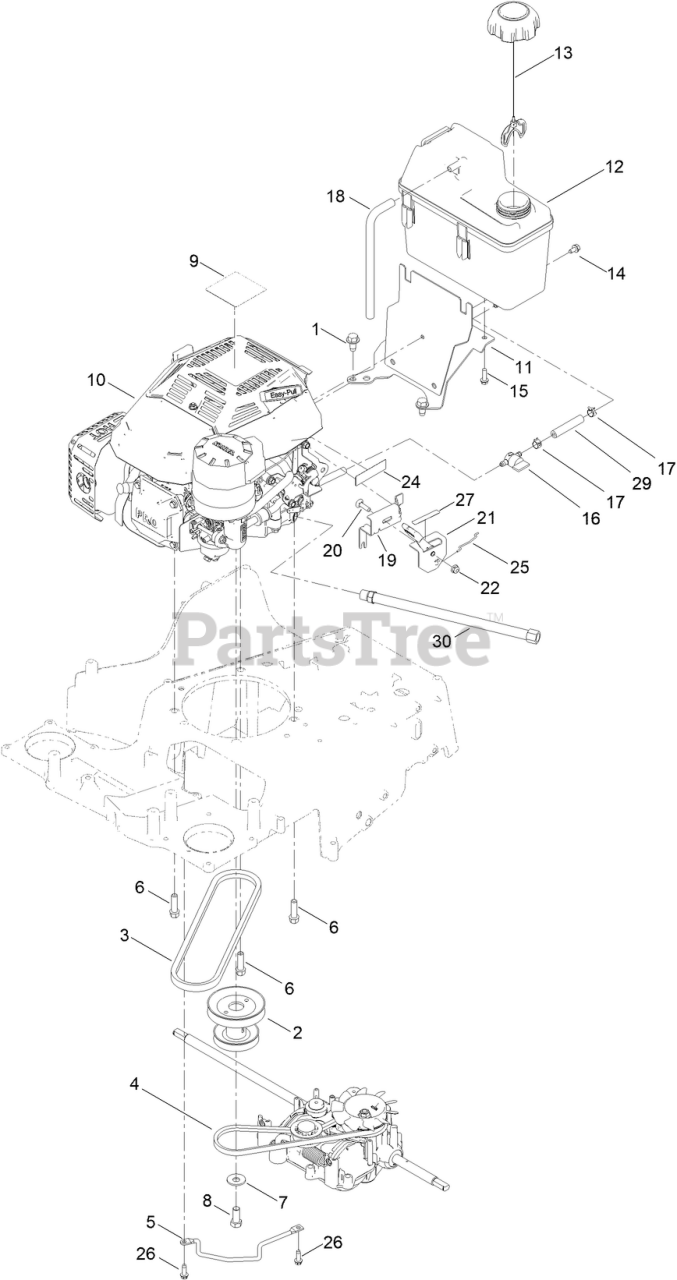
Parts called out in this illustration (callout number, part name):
1	SCREW-HWH
2	PULLEY-ENGINE
3	V-BELT
4	BELT-V
5	ROD-GUIDE, BELT
6	SCREW-TAPTITE
7	WASHER-BELLEVILLE
8	SCREW-HH
9	DECAL-TORO
11	TANK MOUNT ASM
12	TANK-FUEL
13	CAP-FUEL
14	SCREW-HWH
15	SCREW-HWH
16	VALVE-FUEL
17	CLAMP-HOSE
18	HOSE-VENT, CANISTER
19	BRACKET-THROTTLE
20	SCREW-CARR
21	CONTROL-THROTTLE
22	NUT-HF
24	DECAL-WARNING, ENGINE
25	WIRE-LINK
26	SCREW-HWHTF
27	DECAL-THROTTLE, CHOKE
29	HOSE-FUEL
30	HOSE-DRAIN, OIL
